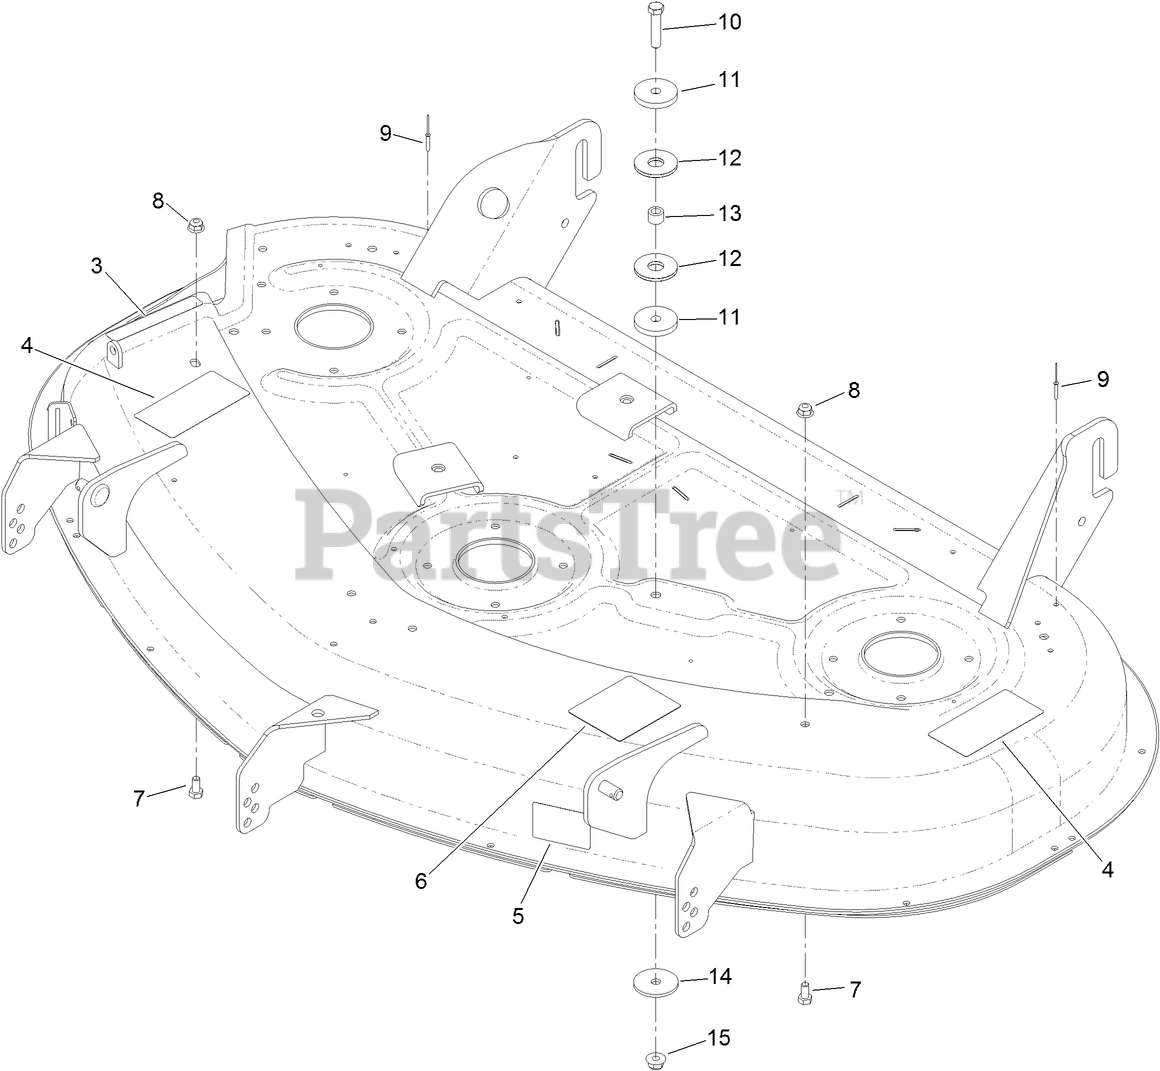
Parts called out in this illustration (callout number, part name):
3	DECAL-DANGER
4	DECAL-DANGER, DECK
5	DECAL-SCALP, ANTI
6	DECAL-ROUTING, BELT
7	SCREW-HH
8	NUT-HF, NI
9	RIVET-BLIND
10	SCREW-HH
11	WASHER-PLAIN
12	WASHER-FRICTION, COMPOSITE
13	SPACER
14	WASHER-REBOUND
15	NUT-HF, NI
